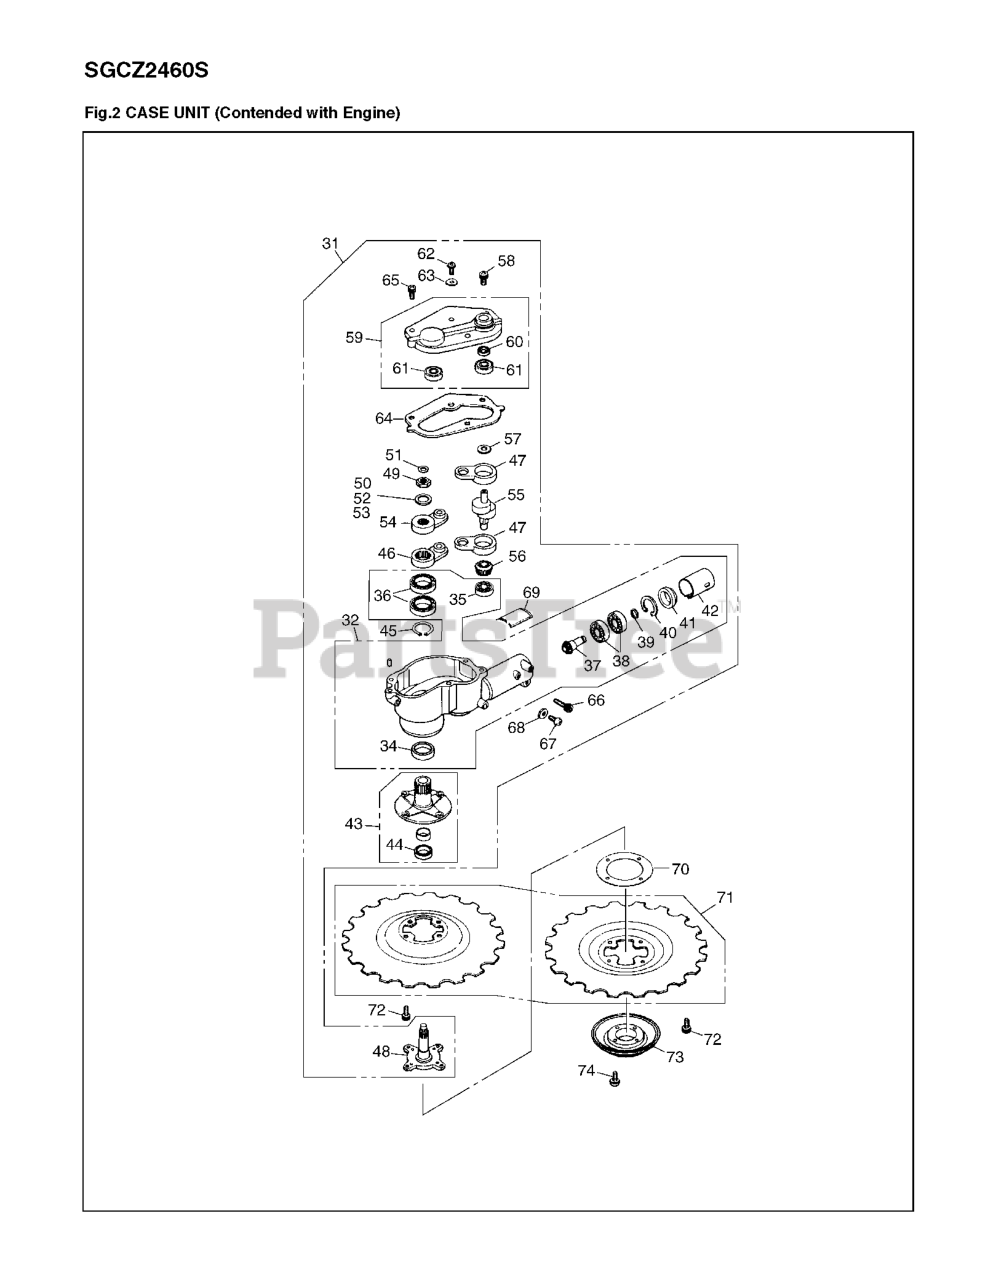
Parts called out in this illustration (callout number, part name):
31	CUTTERCASE ASSEMBLY
32	CUTTERCASE (R-98100&380598100)
34	SEAL, OIL
35	BEARING (RPL 06000-00608)
37	PINION
39	RING, SNAP
40	RING,SNAP M26x1.2 RP-318013340
41	PACKING
42	SPACER (RPLS 3805-13950)
43	SHAFT, OUTER-C
44	SEAL, OIL
45	RING, SNAP, M20 x 1.2
46	ARM, LOWER (RPLS 380513411)
47	CONROD (RPLS 380513431-32)
48	SHAFT, INNER
49	NUT
50	SHIM, 0.3t
51	SHIM
52	SHIM, 0.2t
53	SHIM, 0.1t
54	ARM, UPPER (RPLS 380513611)
55	CRANKSHAFT (RPLS 380513710)
56	GEAR
57	WASHER, M8 x 1.2
58	BOLT
59	COVER COMP
60	SEAL, OIL
61	BEARING (RPL 06000-00608)
62	SCREW, M6 x 10
63	WASHER, M6 x .8
64	GASKET
65	BOLT, M5 x 20
66	BOLT, M6 x 1.35
67	SCREW, M5 x 14
68	WASHER
69	LABEL, CAUTION
70	SHIM
71	SGC BLADE KIT (2 BLADES/SET)
72	BOLT, M6 x 8
73	STABILIZER (RPLS 380515151)
74	SCREW, M5x8 (RPLS 026000508)
